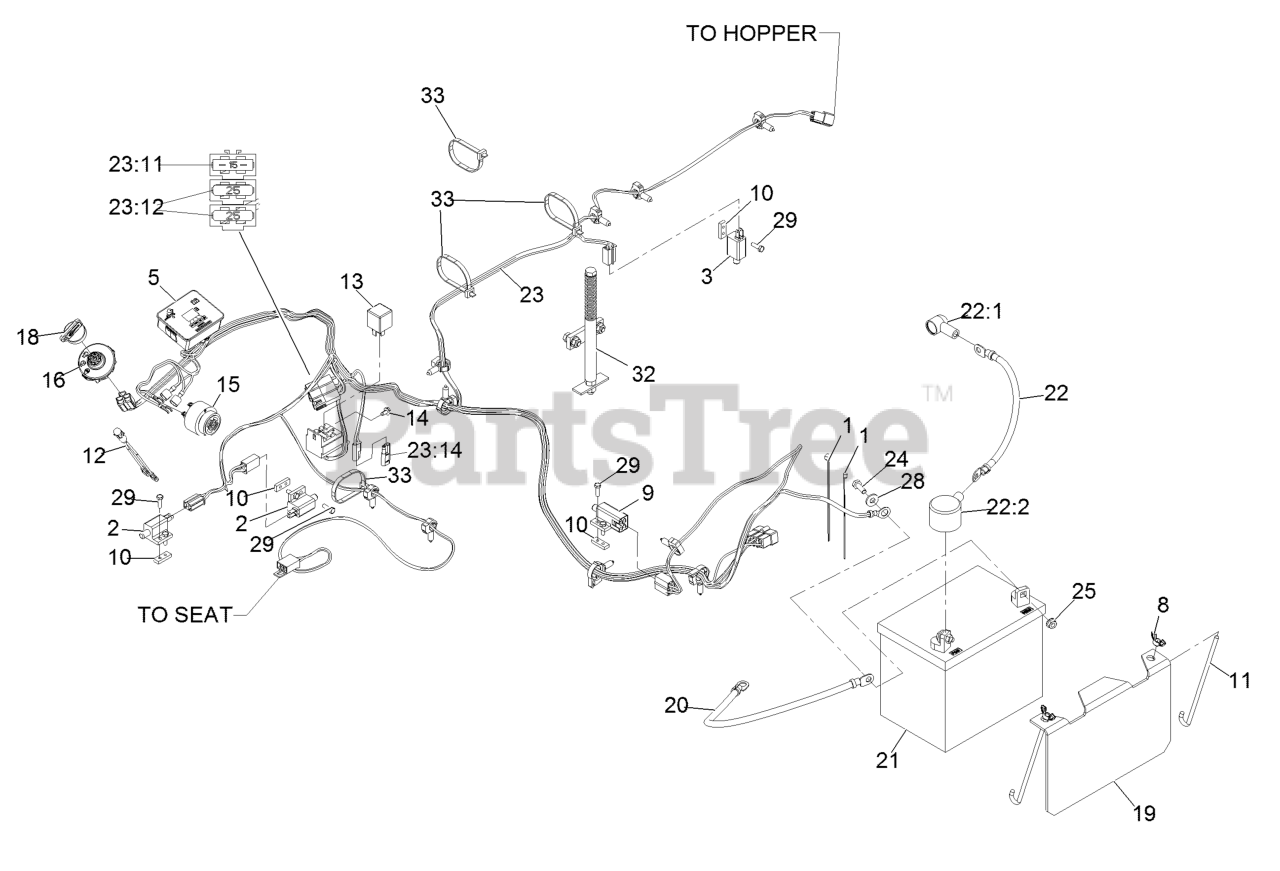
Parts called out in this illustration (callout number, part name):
1	TIE-CABLE
2	SWITCH-OPEN, NORMALLY
3	SWITCH-CLOSED, NORMALLY
5	HOUR METER ASM
8	WINGNUT
10	PLATE-TAPPED
11	BOLT-HOLDDOWN
12	INDICATOR-LED, RED
14	SCREW-HWH
15	ALARM-TONE, DUAL
18	KEY-IGNITION
19	HOLD DOWN-BATTERY
20	CABLE-BATTERY, NEGATIVE
21	Battery (300 Cca, Wet)
22	CABLE-BATTERY, POSITIVE
22:1	INSULATOR-SOLENOID
22:2	INSULATOR-BATTERY
23	HARNESS-WIRING
23:11	FUSE-BLADE, 15 AMP
23:12	FUSE-BLADE, 25 AMP
23:14	CAP-PLUG
24	SCREW-HH
28	WASHER-FLAT
32	HOPPER SWITCH ACTUATOR AS
33	TIE-PLASTIC
